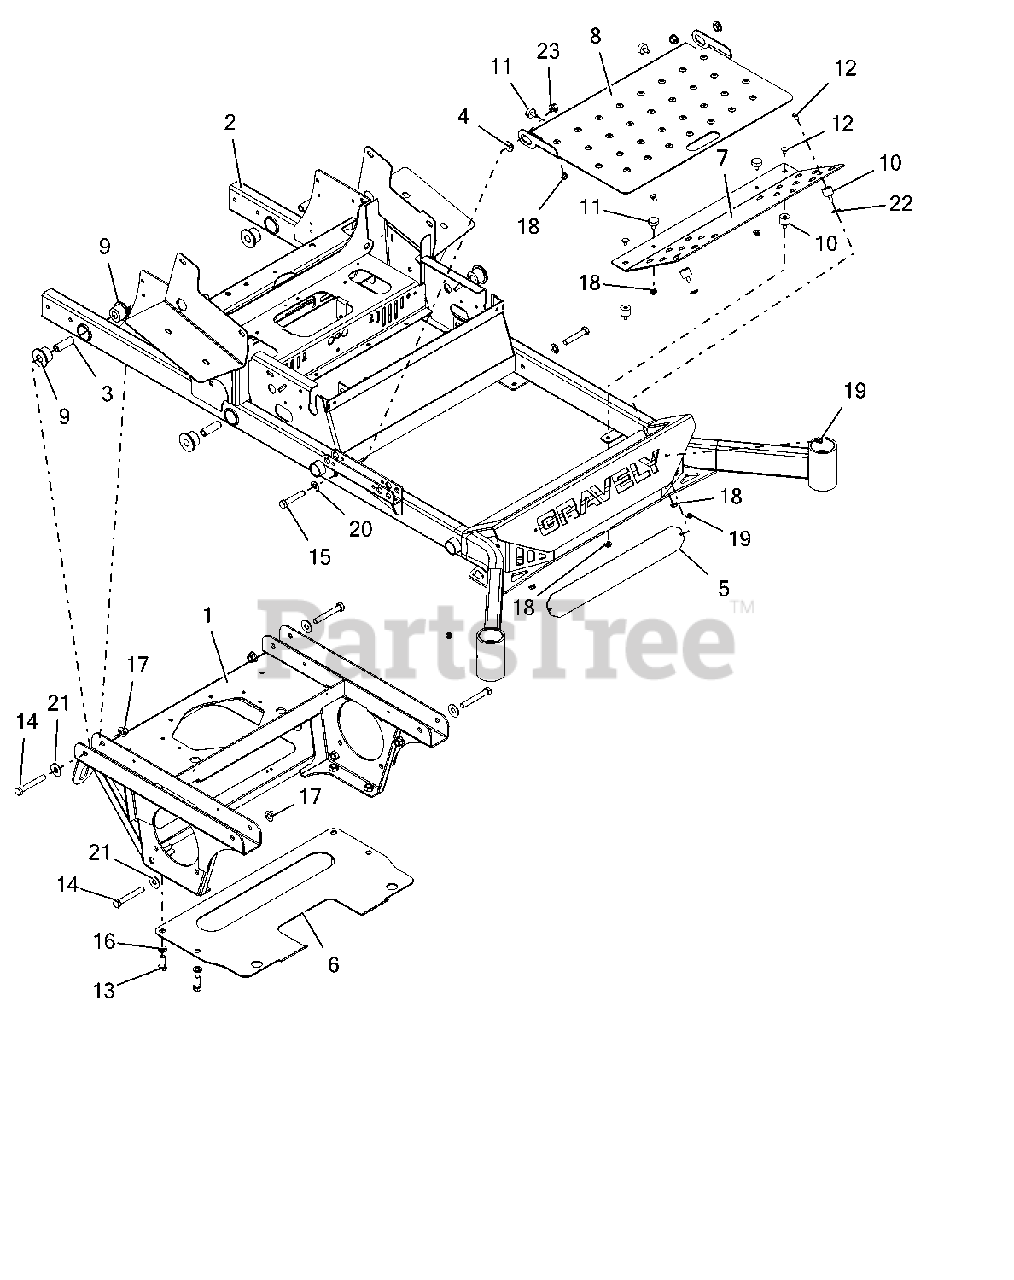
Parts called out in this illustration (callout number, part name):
1	PT200/400 AXLE/ENG FRM WMT-RED
2	72" PT200/400 FRAME W/DECALS
3	BSHG-SLV .50X.75X2.23
4	BSHG-FLG .515X.750X.395X1.120
5	BUMPER LOGO BACKING PLATE -BLK
6	PLATE-TRANSMISSION SKID
7	FOOTREST W/ SAFTEY DECALS
8	INSPECTION PANEL W/SAFE DECAL
9	BSHG-FLG .75X1.51X1.13X2.0 URE
10	BUMPER,STUD MNTD W/FEMALE INSR
11	BUMPER, RUBBER
12	BLT-RDHDSQNK .31-18X.50 G5YZ
13	BLT-HEX .50-13X1.25 GR5 YWZC
14	BLT-HEX .50-13X3.50 GR5 YWZC
15	BLT-HEX .50-13X2.75 GR5 YWZC
16	WSHR-LK .50X.125 REG YWZC
17	NUT-LK-NYL-FLG .50-13 YWZC
18	NUT-SPNLK-FLG .312-18 YWZC
19	SCR-TAP .25-20X.50 HWH TR YWZ
20	WSHR-FL-STL.531X1.00X.063 YWZC
21	WSHR-FL-STL.563X1.38X.109YWZC
22	WSHR-FL-STL.38X.875X.083 YWZC
23	NUT-LK-CTR-FLG .50-13 YWZC
